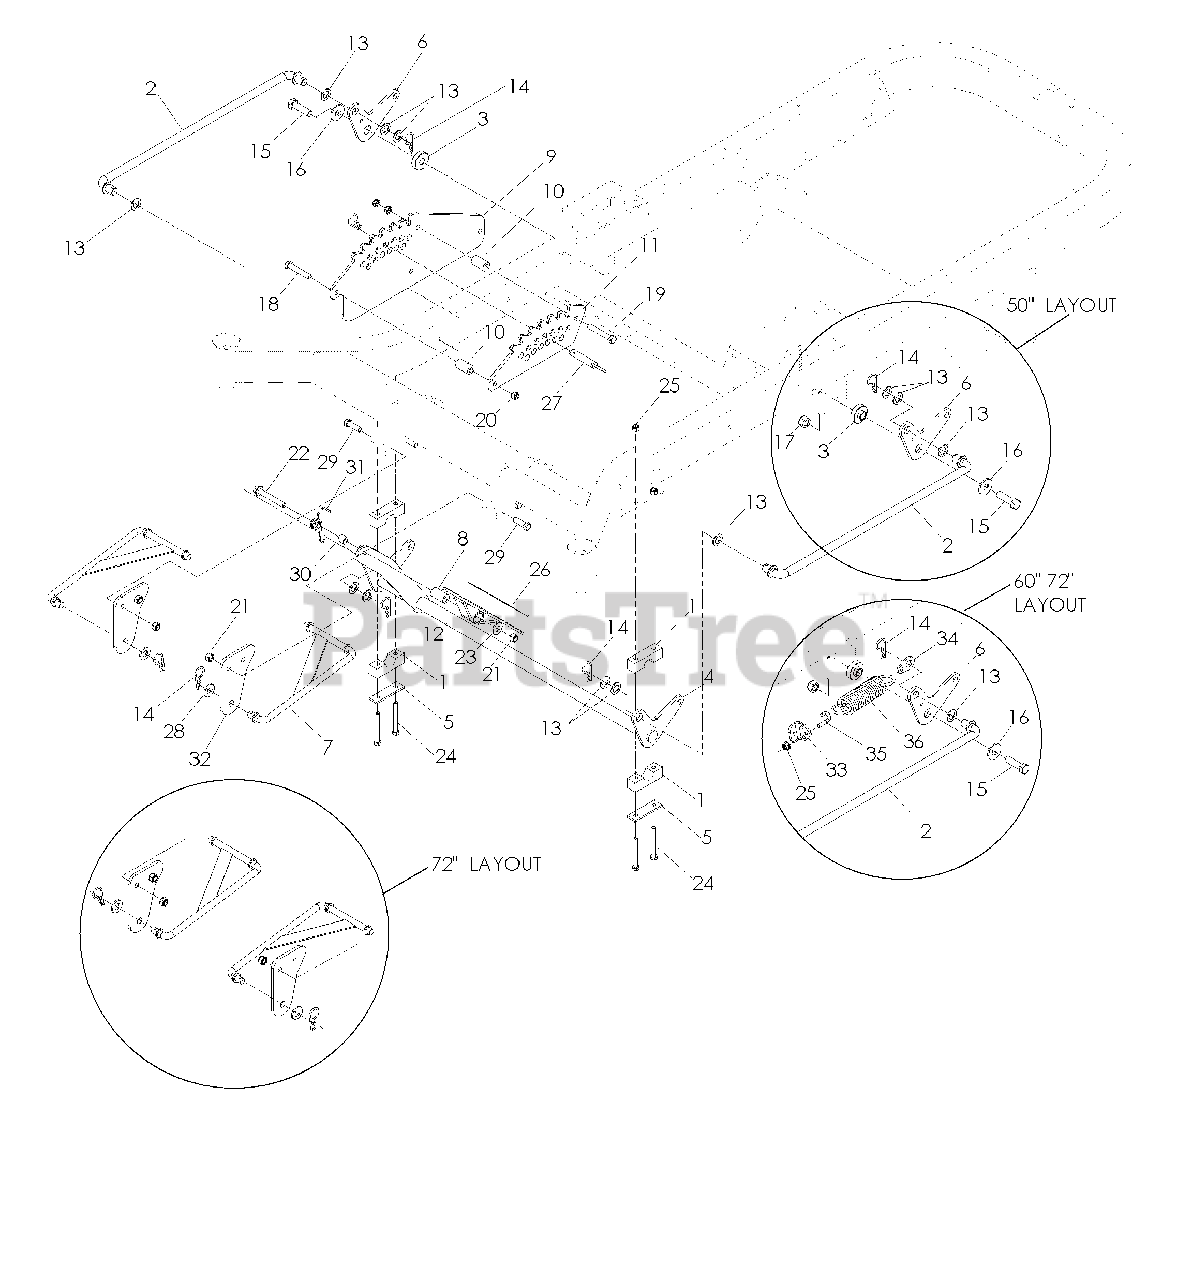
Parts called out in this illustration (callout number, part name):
1	PILLOW BLOCK
2	CROSS LINK
3	IDLER SPACER
4	SHAFT, LIFT, DECK
5	REINFORCEMENT BAR
6	BELLCRANK, REAR LIFT
7	STRUT LINKAGE
8	BUSHING, SLEEVE
9	PLATE, HEIGHT, MAIN, BLUE
10	DECK LIFT SPACER
11	PLATE, HEIGHT, BLUE
12	PEDAL, FOOT, WELDMENT
13	BUSHING
14	PIN, COTTER 1 3/4
15	HCS 1/2-13 X 1 3/4 GR 8
16	WASH USS FLAT 1/2
17	NUT 1/2-13 HEX NYLOC ZD
18	HCS 3/8C X 2 1/4
19	HCS 3/8C X 2 1/2
20	NUT HEX 3/8-16 NYLON, THIN
21	NUT 3/8-16 NYLOC
22	HHFS 3/8-16 X 2 3/4
23	WASHER 3/8 FLAT
24	HCS 5/16C X 2-3/4
25	5/16-18 NYLOC FLANGE NUT
26	FOOT PAD
27	HITCH PIN
28	WASHER 1/2" FLAT
29	HCS 3/8C X 1 1/4 GR5
31	SPRING, TORSION
32	MOUNT, STRUT
33	MOUNT, SPRING
34	TAB, SPRING
